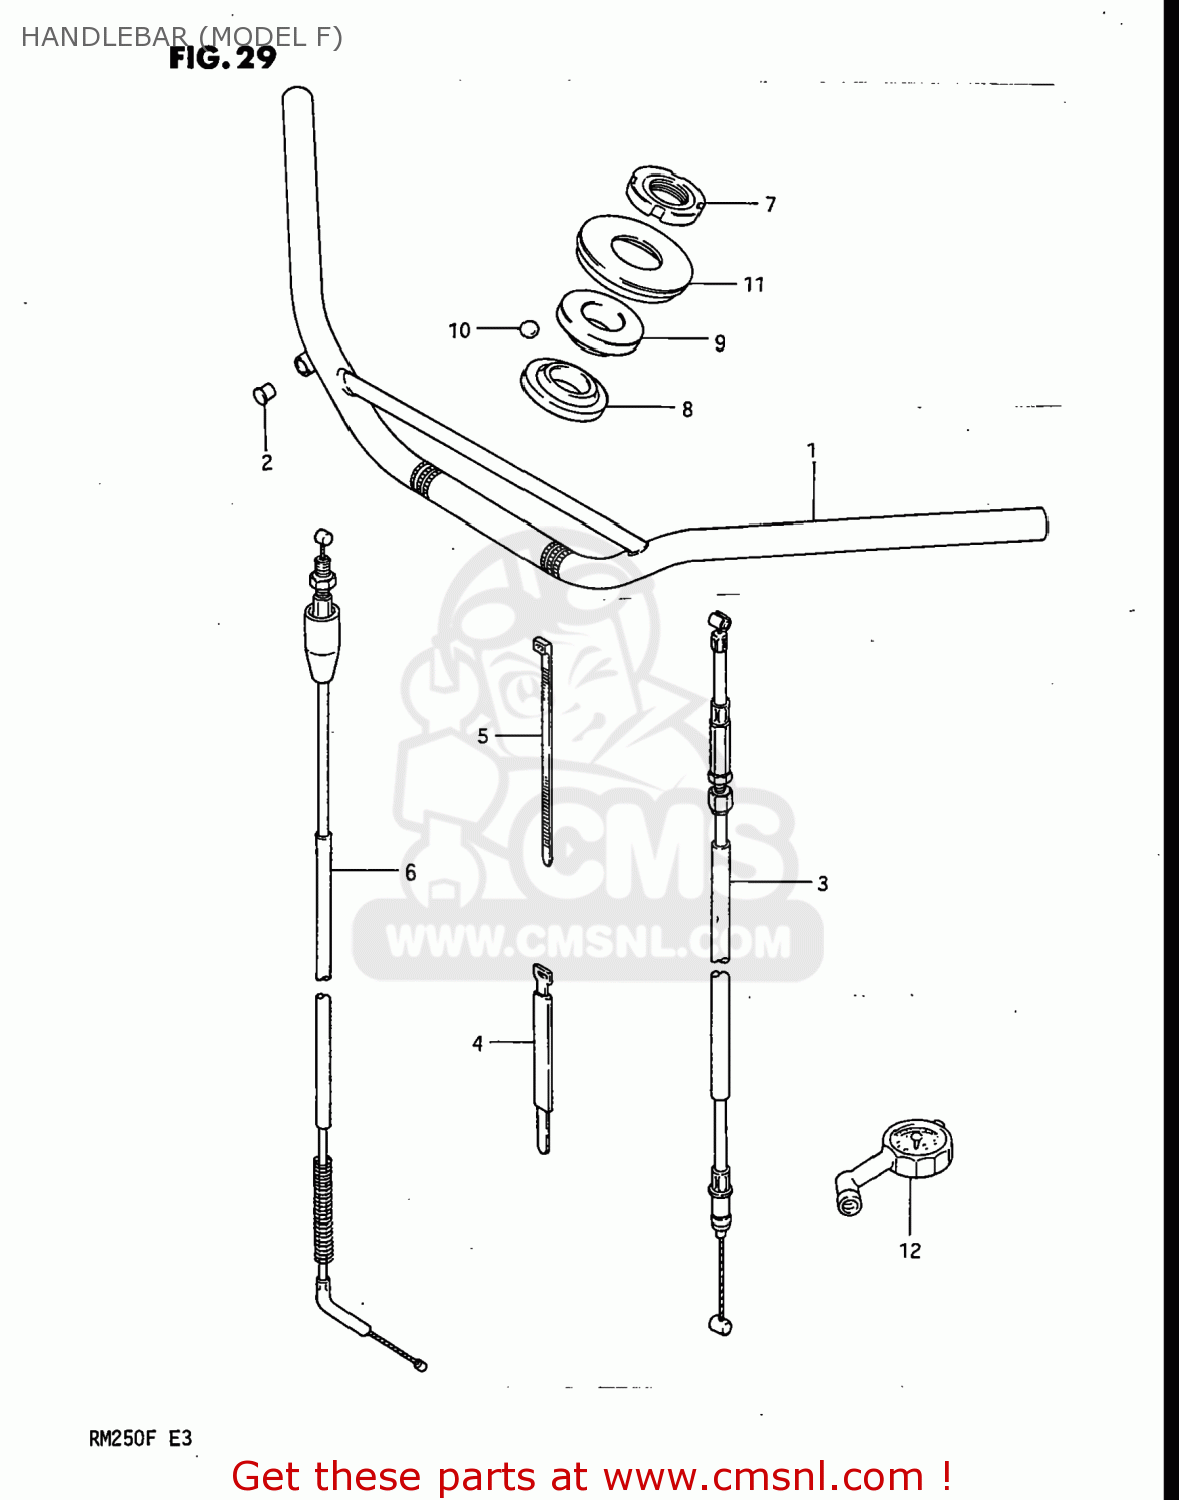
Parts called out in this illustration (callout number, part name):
1	HANDLEBAR
2	CAP(OD:14)
3	CABLE ASSY,CLUTCH
4	CLAMP
5	CLAMP(L:235)
6	CABLE ASSEMBLY,THROTTLE
7	NUT,STEERING STEM
8	RACE,STEERING,INNER,UPPER
9	RACE,STEERING,OUTER,UPPER
10	BALL
11	SEAL,STEERING UPR DUST
12	GAUGE ASSY,AIR PRESSURE
